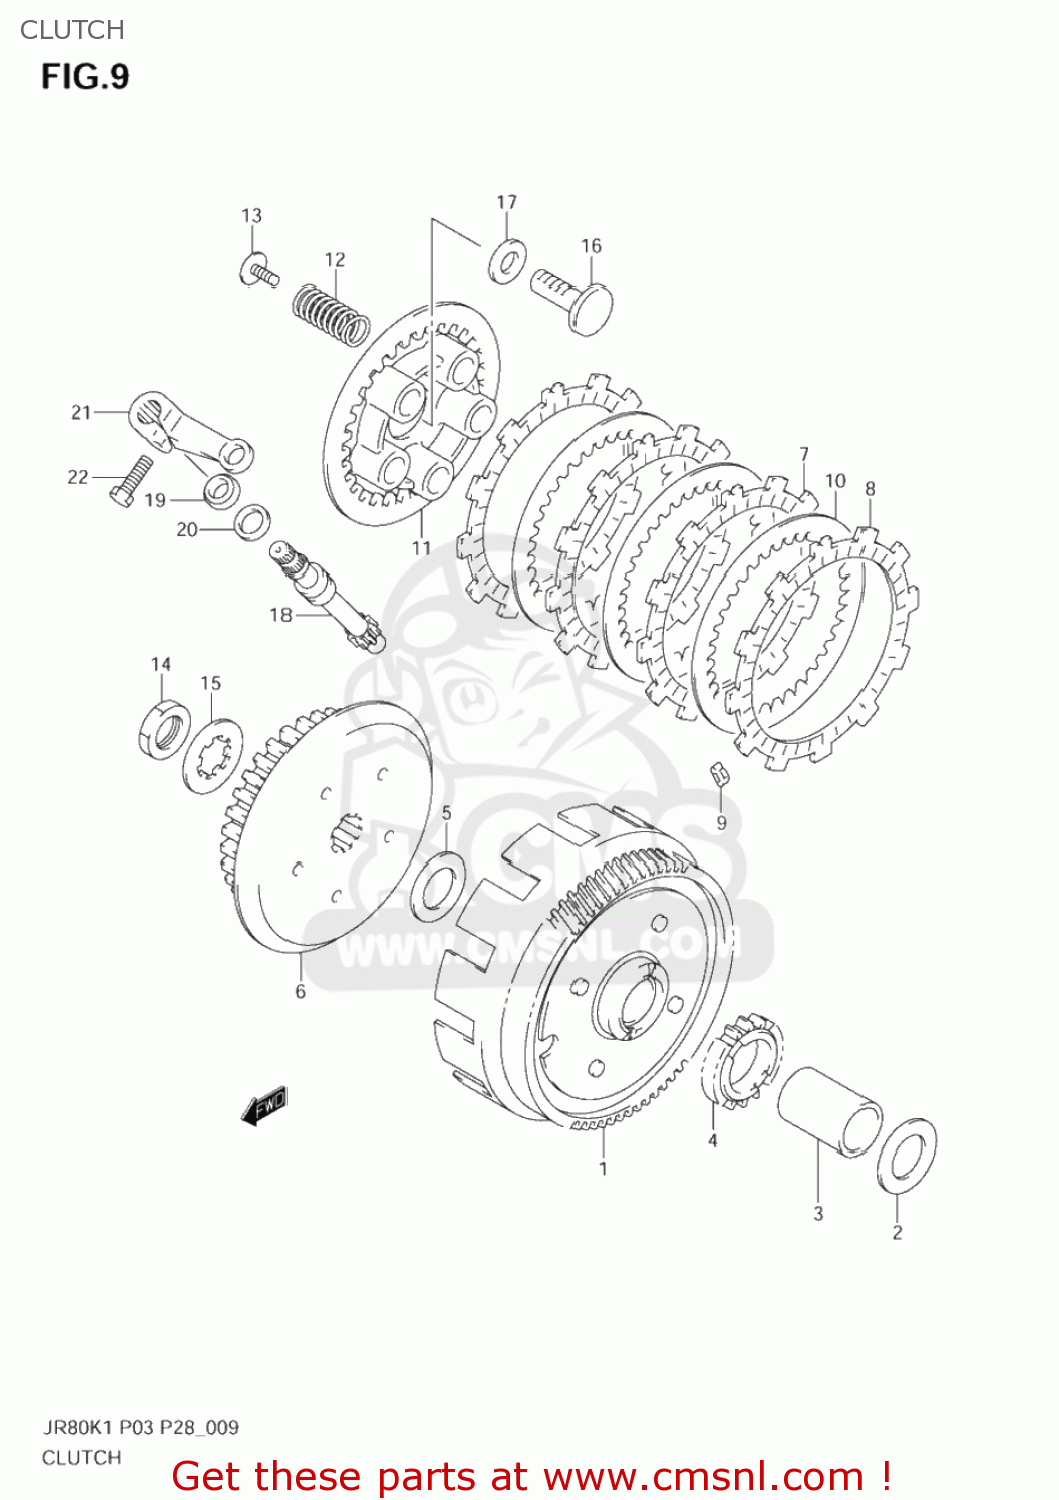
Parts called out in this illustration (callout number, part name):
1	GEAR ASSY,PRI DRIVEN(NT:73)
2	WASHER(21X30X1)
3	SPACER,PRIMARY DRIVEN GEAR
4	GEAR,KICK STARTER DRIVE
5	WASHER
6	HUB,CLUTCH SLEEVE
7	PLATE,CLUTCH DRIVE(T:3.0) (NAS)
8	PLATE,CLUTCH DRIVE (NAS)
9	DAMPER
10	PLATE,CLUTCH DRIVEN (NAS)
11	DISC,CLUTCH PRESSURE
12	SPRING
13	BOLT(5X16)
14	NUT
15	WASHER,LOCK
16	RACK,CLUTCH RELEASE
17	BEARING(10X22X2.8)
18	PINION,CLUTCH RELEASE
19	SEAL,OIL(10X17X5)
20	WASHER(12.5X17X1)
21	ARM,CLUTCH RELEASE
22	BOLT
